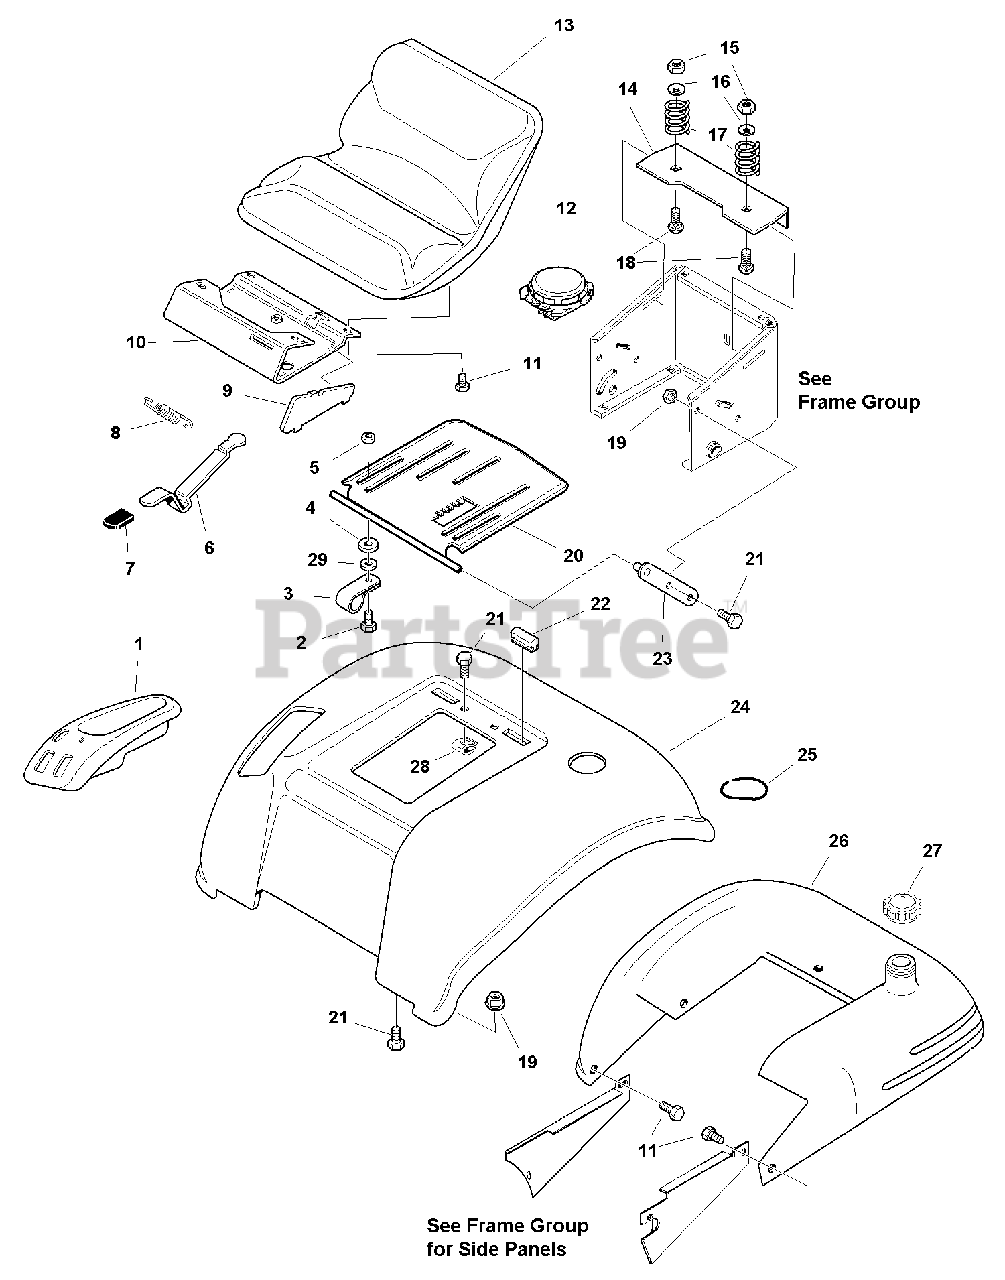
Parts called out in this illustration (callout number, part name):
1	POD, Control
2	SCREW, Torx Truss Head, 5/16-18 x 7/8, Black
3	CLAMP, Wire
4	WASHER, Curved, Special
6	LEVER, Seat Latch, Black
8	SPRING, Extension, 4-1/4 Long
9	PANEL, Side
10	SLIDE, Seat
11	CAPSCREW, Hex Head Whiz Lock, 5/16-18 x 1/2, Black
12	SEAT SWITCH, NC
13	SEAT W/Cushion & Sensitivity
14	PLATE, Spring
15	NUT, Hex Lock ESNA, 5/16-18, Black
16	WASHER, Spring
18	CARRIAGE BOLT, 5/16-18 x 1, Black
19	NUT, Hex Whiz Lock, 5/16-18, Black
20	PAN & ROD ASEMBLY
21	CAPSCREW, Hex Head, Whiz Lock, 5/16-18 x 3/4, Black
25	MOLDING, PCV, 12-3/8" Long
28	NUT, Speed, 5/16-18
29	WASHER, 5/16
